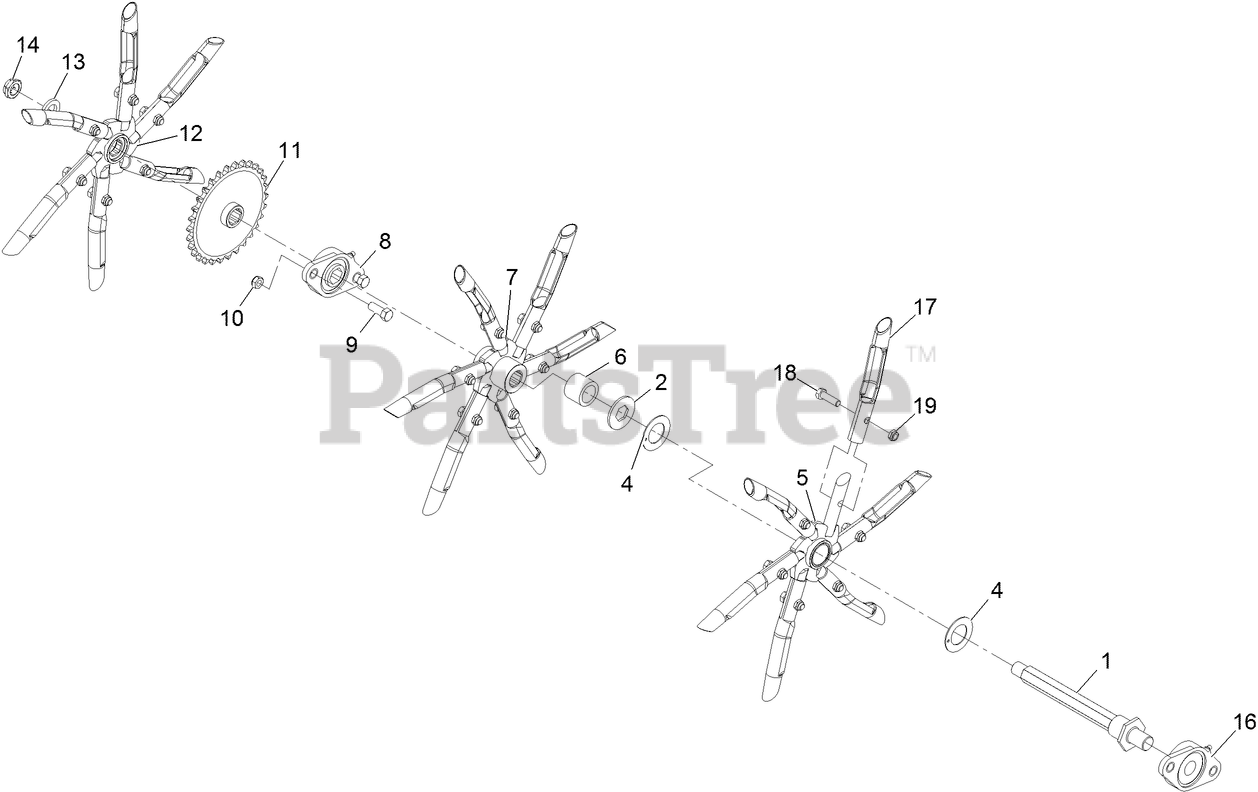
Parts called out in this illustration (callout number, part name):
1	TINE SHAFT ASM
2	KEEPER-TINE, FLOATING
4	WASHER-THRUST
5	FLOATING SPYDER ASM
6	SPACER-TINE
7	DRIVEN SPYDER ASM
8	BEARING-HEX BORE
9	SCREW-HH
10	NUT-LOCK
11	SPROCKET ASM
12	DRIVEN SPYDER ASM
13	WASHER-SPACER
14	NUT-LOCK
16	BEARING-ROUND BORE
17	TINE-CORING (3/4 INCH)
18	SCREW-HH
